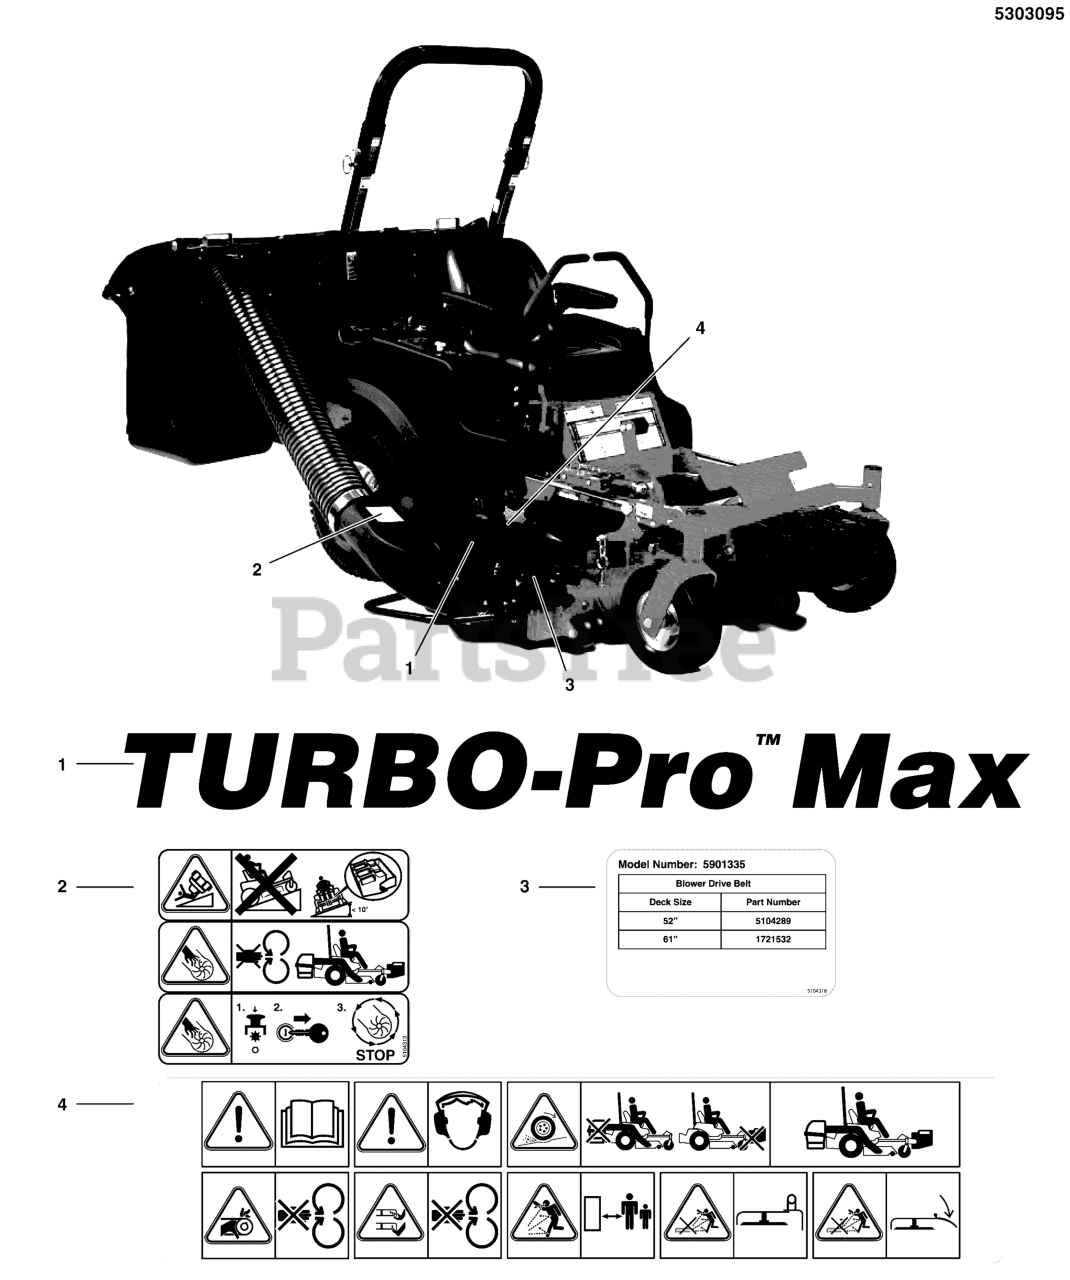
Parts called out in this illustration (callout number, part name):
1	DECAL, TURBO PRO MAX
2	DECAL, BLOWER, SMALL, ICONS
3	DECAL, BELT, TURBO-PRO MAX
4	DECAL, BLOWER, MAIN, LARGE, ICONS
